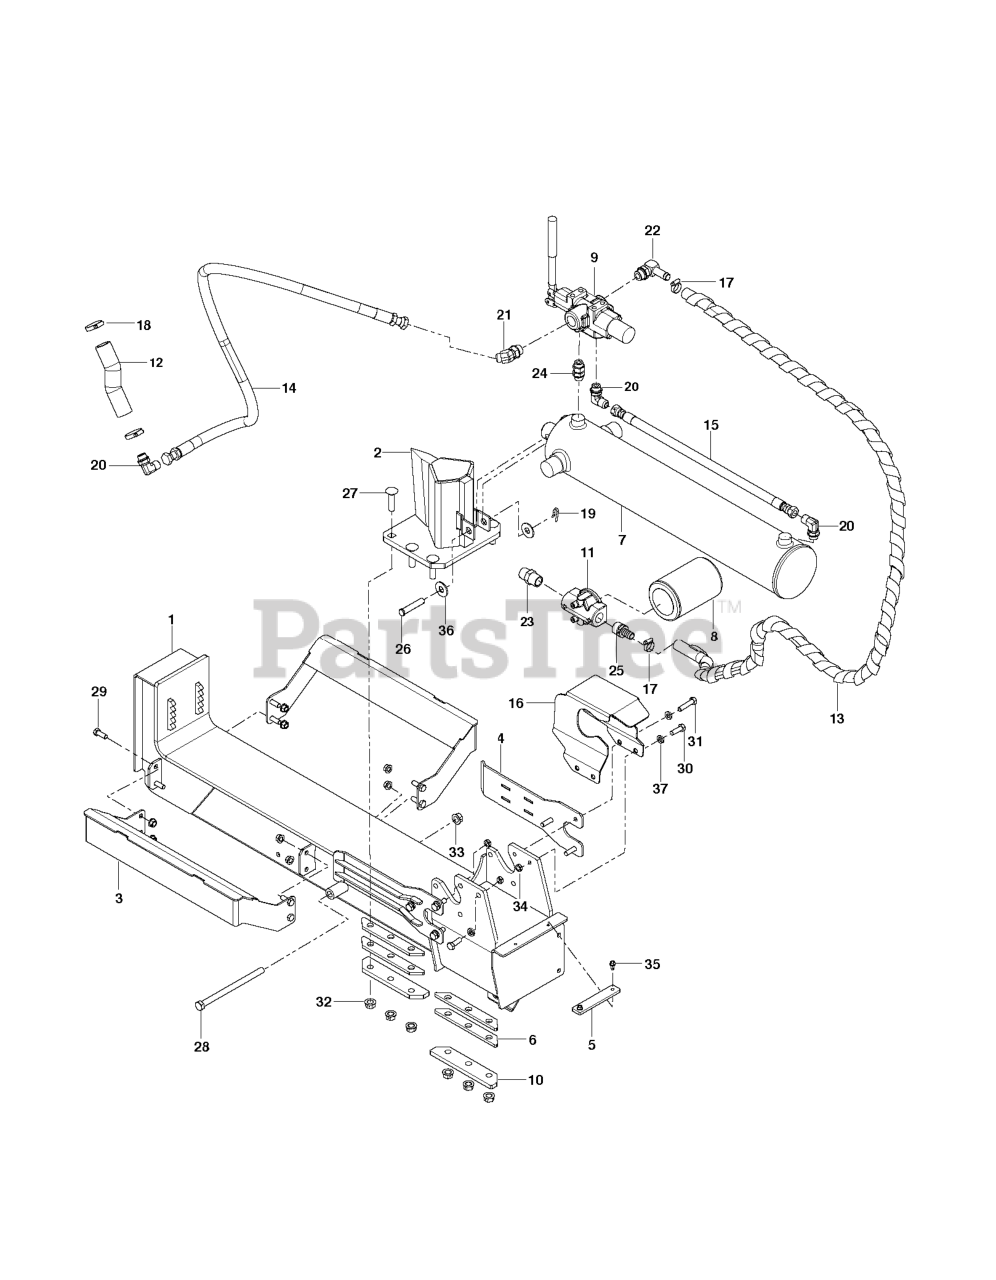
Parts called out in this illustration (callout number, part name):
1	BEAM BEAM-27&34T SPLITTER
2	SPLITTER WEDGE
3	CHASSIS CRADLE-LOG CRADLE
4	PLATE PLATE, STRIPPER
5	SPACER SPACER, CYLINDER
6	SPACER SPACER, WEDGE
7	CYLINDER CYLINDER, SPLITTER -
8	FILTER FILTER,OIL-W/BYPASS
9	CONTROL VALVE CONTROL-SPLITTER
10	RETAINER, WEDGE
11	HEAD, FILTER - 3/4 NPT
12	HOSE HOSE, HYD - SUCTION 6.75"
13	HOSE HOSE,HYD-RET 801-10 WP 74
14	HOSE ASSY, HOSE; 8M3K-8FJX-8FJ
15	HOSE ASSY, 8M3K-8FJX-8FJX-22
16	SHIELD, VALVE
17	CLAMP CLAMP, COUSHIONED STEEL
18	CLAMP CLAMP, CUSHIONED STEEL
20	FITTING FITTING,HYD 6801-8-8
21	FITTING FITTING, HYD 6802-8-10
22	FITTING FITTING, HYD 4601-10-1
23	FITTING FITTING
24	FITTING FITTING, HYD-STR 08MAO
25	FITTING FITTING, HYD 3/4 NPT X
26	PIN PIN, CLEVIS .50 X 2.50 X 2
27	BOLT BOLT RDHDSQNK .50-13X2 G8
28	BOLT BOLT HEX .50-13 X 7.50 GR
29	BOLT BOLT HEX .38-16 X 1.00 GR
30	BOLT BOLT HEX .31-18 X 1.00 GR
31	BOLT BLT-HEX .31-18X1.25 GR5 Y
33	NUT NUT, LK-TOP-FLG .38-16 YWZ
34	NUT NUT, LK-TOP-FLG .31-18 YWZ
36	WASHER WASHER, FL-STL.563X1.38
37	WASHER WSHR-LK .31X.097 HVY YW
